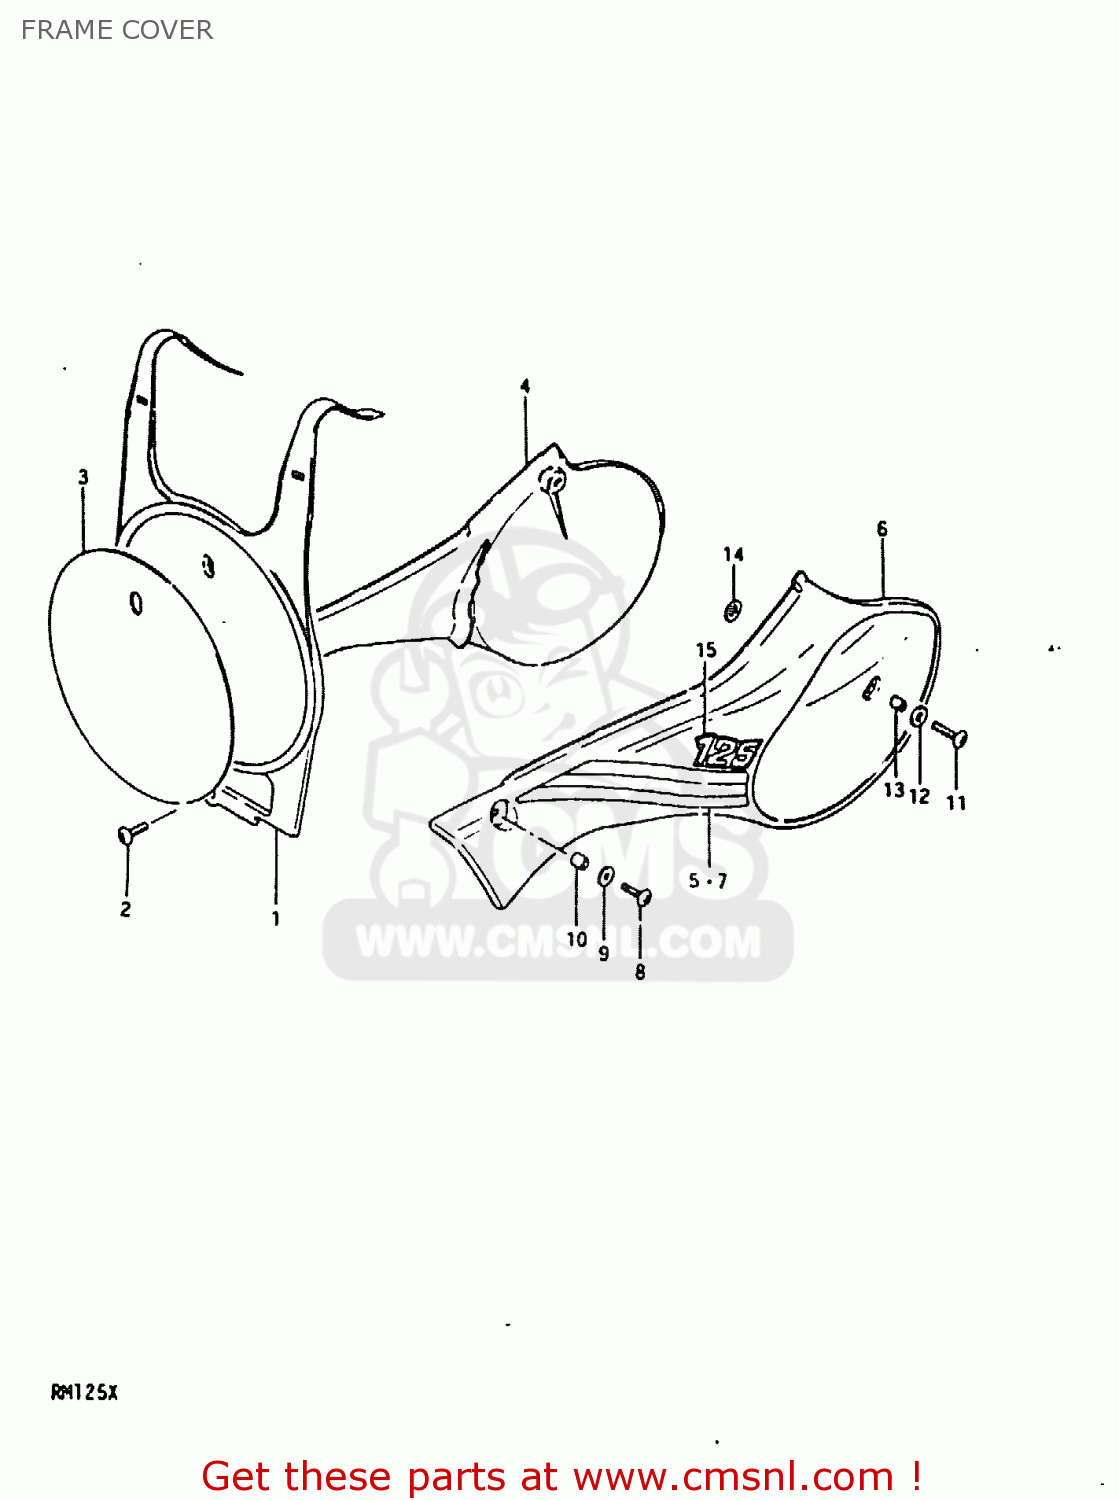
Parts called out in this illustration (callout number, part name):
1	PLATE,NUMBER,FRONT
2	(5X20) CROSS SCREW
3	EMBLEM,FRONT NUMBER PLATE
4	COVER,FRAME,RIGHT
5	TAPE, RH
6	COVER,FRAME,LEFT
7	TAPE, LH
8	SCREW
9	WASHER FRAME COVER
10	SPACER,FRAME COVER,FRONT
11	SCREW
12	WASHER FRAME COVER
13	SPACER FRAME COV RR
14	GASKET
15	EMBLEM
